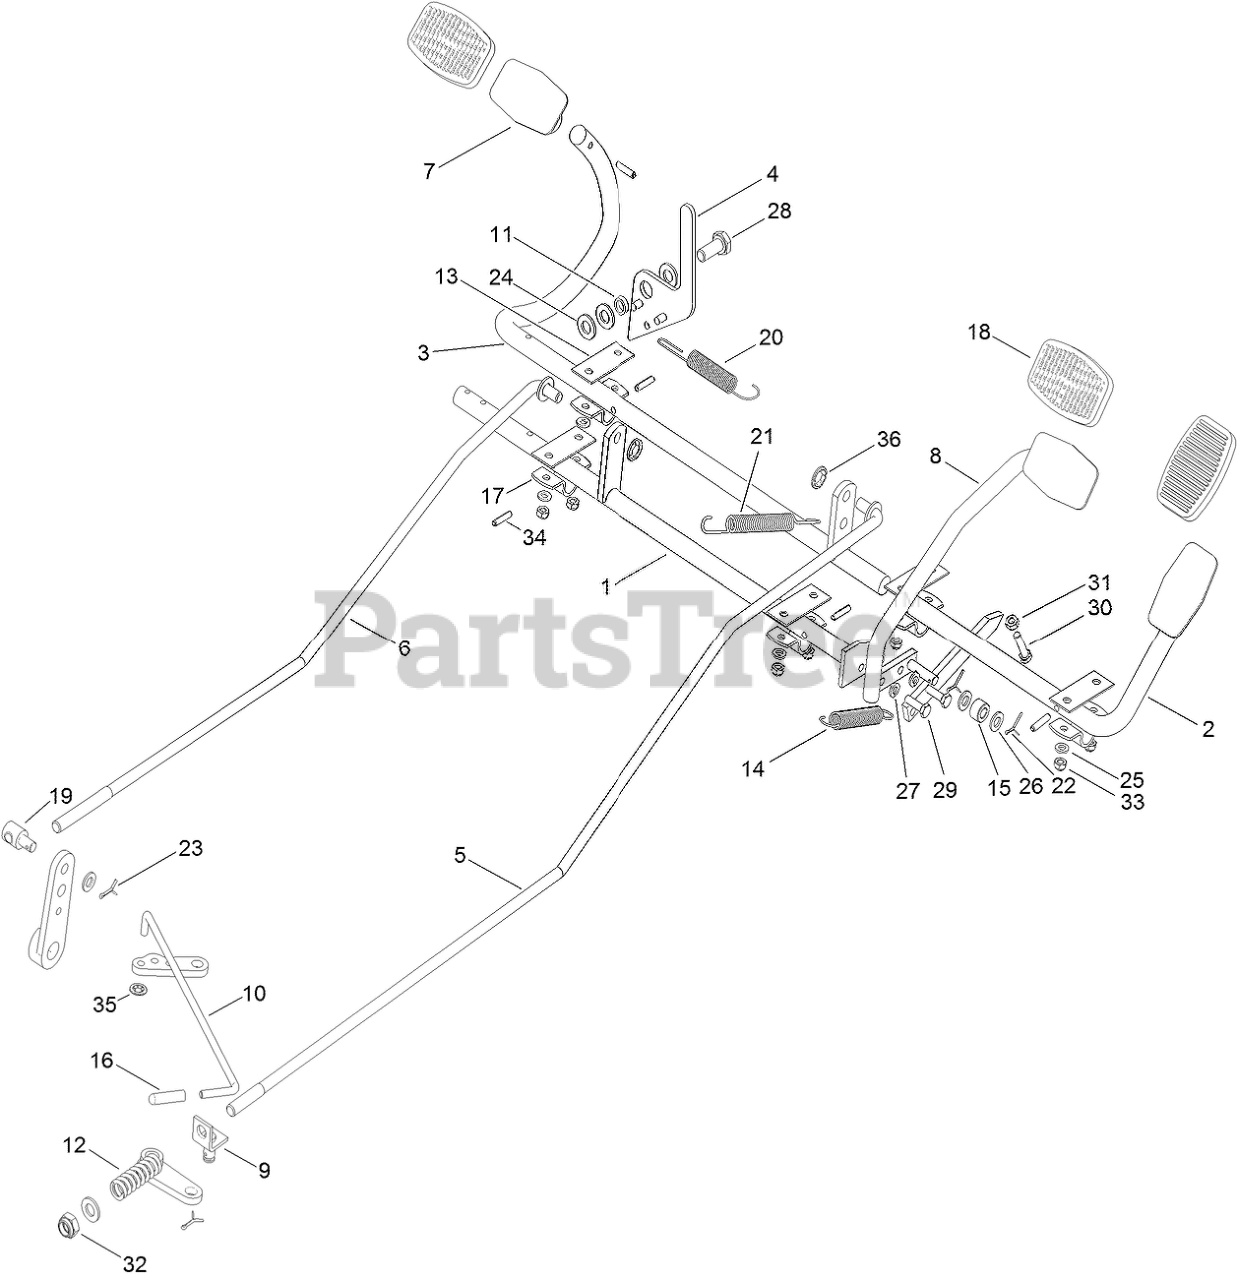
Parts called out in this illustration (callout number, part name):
1	SHAFT-DIAGONAL
2	PEDAL-TRAVEL, REAR
3	PEDAL-BRAKE
4	LEVER-BRAKE, HAND
5	ROD-CONNECTING, BRAKE
6	ROD-TIE
8	PEDAL-TRAVEL, FORWARD
9	BRACKET-ROD, BRAKE
10	ROD-LEVER, BYPASS
11	SPACER
12	SPRING-BRAKE
13	SPACER
14	SPRING
15	Roller
16	CAP-BYPASS LEVER, HYDRO
18	PAD-PEDAL
20	SPRING-BRAKE, HAND
21	SPRING
22	PIN-COTTER
23	PIN-COTTER
24	WASHER-FLAT
25	WASHER
26	WASHER-PLAIN
27	WASHER-SPRING
28	SCREW-HEX
29	SCREW-HH
30	SCREW-HH
31	NUT-HEX
32	NUT-LOCK, NI
33	NUT-LOCK
34	PIN-SPRING
35	RING-LOCKING
36	RING-LOCKING
